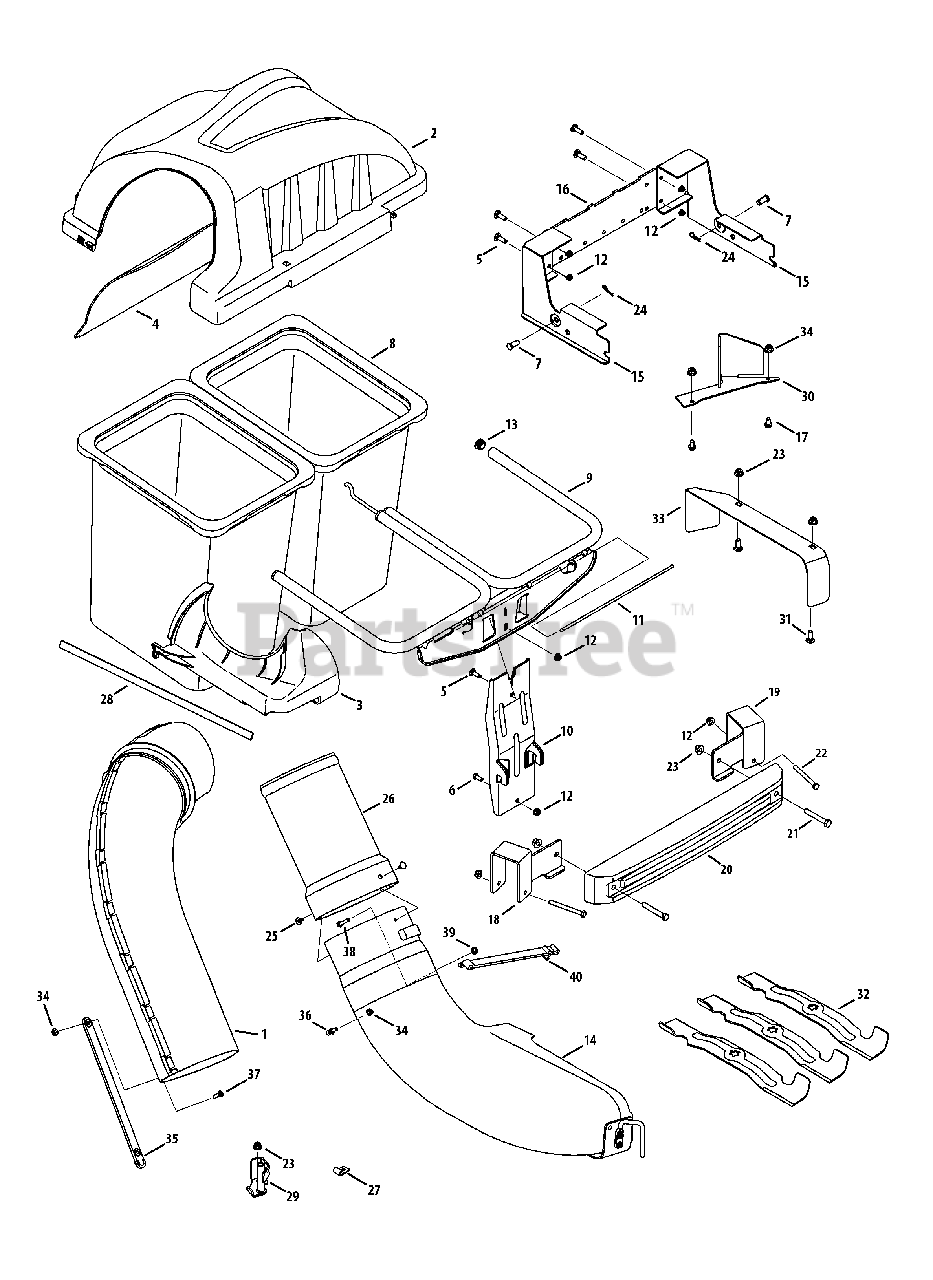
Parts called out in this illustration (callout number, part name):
1	Upper Chute Assembly
2	Twin Bagger Cover Assembly
3	Upper Chute Support
4	Bagger Cover Screen
5	Carriage Screw, 5/16-18 x 1.00"
6	Hex Head Screw, 5/16-18 x .75"
7	Clevis Pin, .50" Dia.
8	Grass-bag Assembly
9	Twin Bag Support Assembly
10	Vertical Support Bracket
11	Cover Hinge Pin
12	Flange Lock Nut, 5/16-18
14	Discharge Chute Elbow
15	RZT Hitch Bracket Kit (RH & LH)
16	Universal Cross Bracket
17	Hex Head Screw, 1/4 - 20 x .75
18	Weight Mount Bracket, RH
19	Weight Mount Bracket, LH
20	Bagger Weight
21	Hex Head Screw, 3/8 - 16 x 2.50
22	Hex Head Screw, 5/16-18 x 3.25
23	Flange Lock Nut, 3/8 - 16
24	Cotter Pin, .080 x 1.5625 Internal
25	Ratchet Clip, .250
25	Hex Head Screw, 1/4-20 x .5 Gr 5
25	Acorn Hex Nut
26	Bagger Chute Adapter, 8 x 13.5
27	Retainer Hook Bracket
28	Adhesive Strip
29	Chute Stop Bracket
30	Deck Baffle, 50"
31	Carriage Bolt, 3/8-16 x 1.00
32	Bagging Blade, 17.90 Lg. Star
33	Chute Discharge Plate
34	Flange Lock Nut, 1/4-20
35	Chute Strap
36	Grass-catcher Pin
37	Machine Screw, 1/4-20
38	Hex Head Screw, 1/4-20 x .75
39	Flange Lock Nut, 1/4-20
40	Chute Strap
